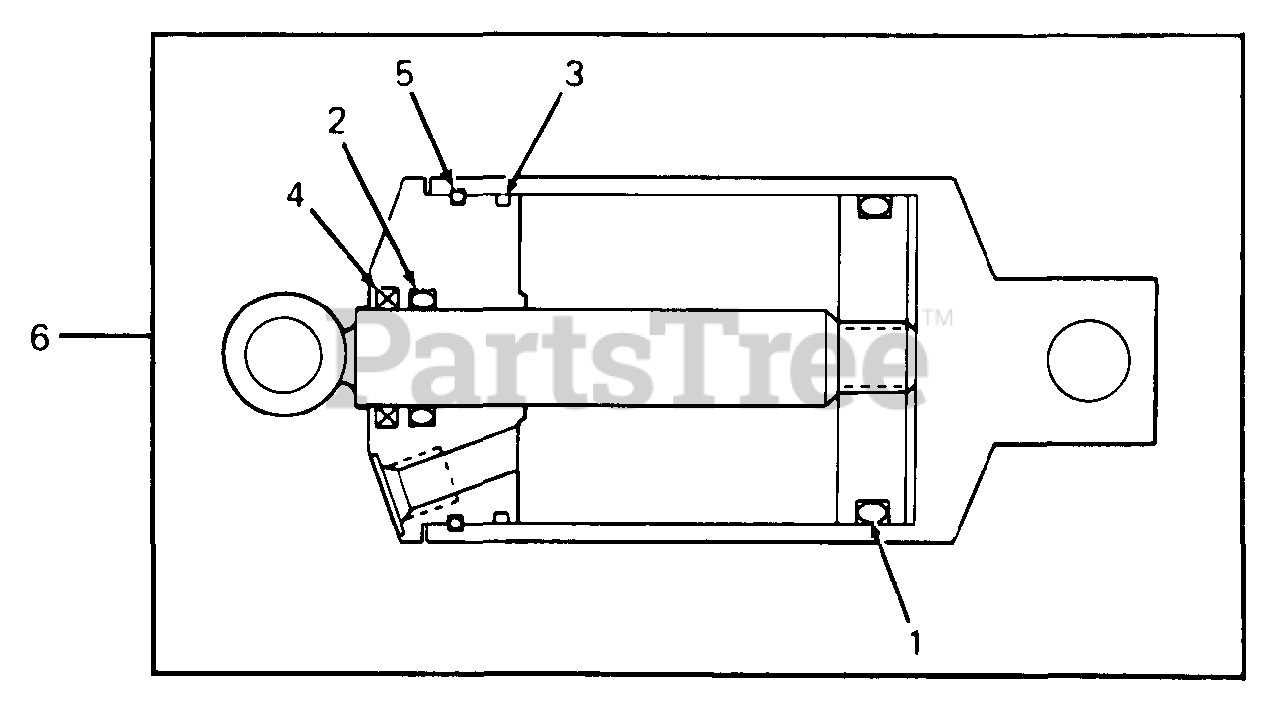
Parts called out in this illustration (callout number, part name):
4	Seal, Hydraulic Cylinder
5	Retainer, Hydraulic Cylinder
6	Cylinder, Hydraulic
